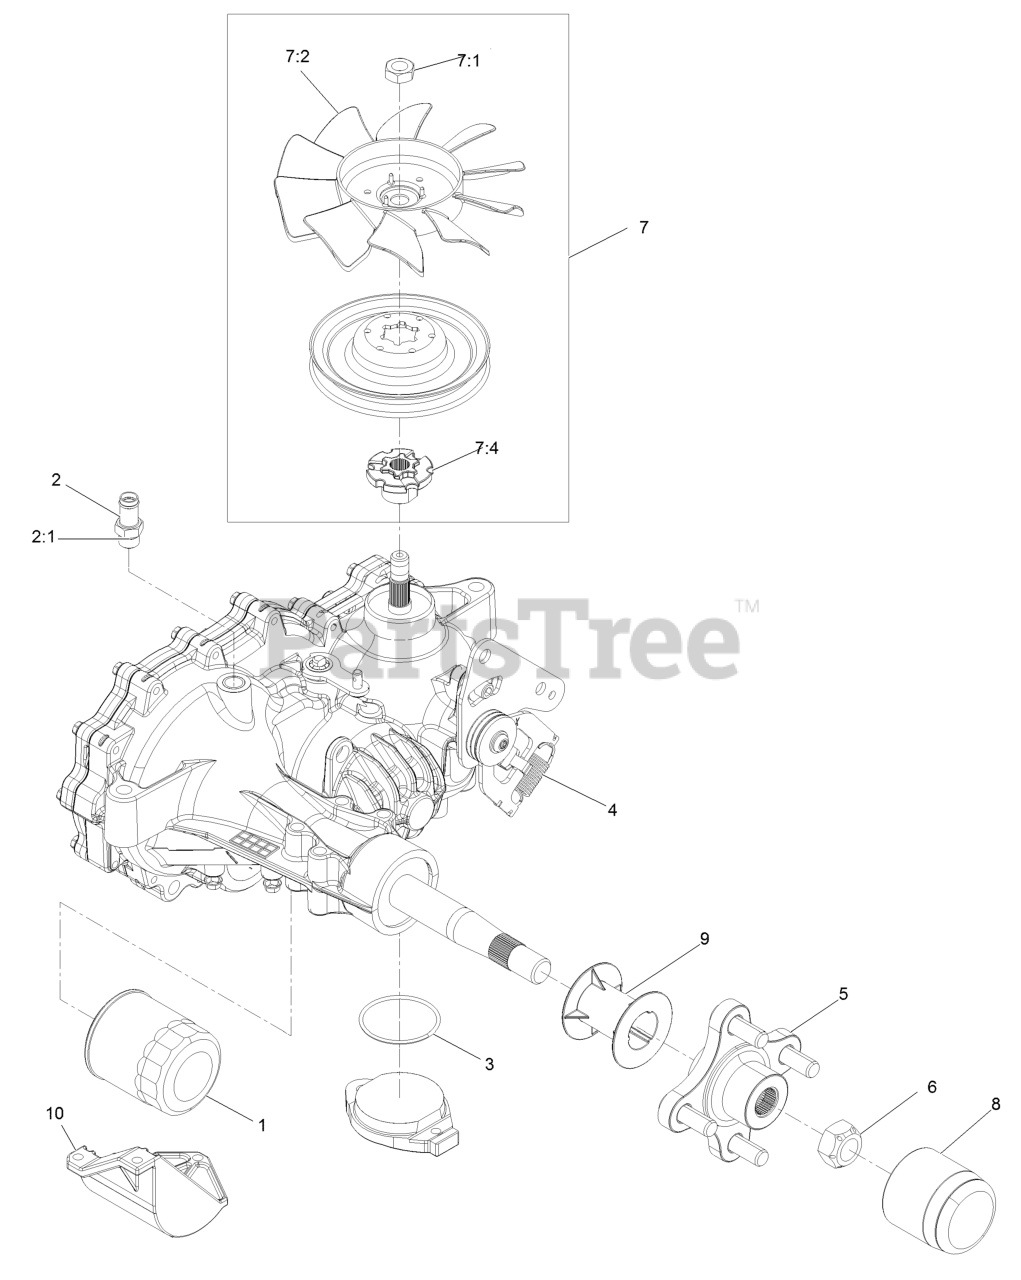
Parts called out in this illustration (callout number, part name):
1	Element-Oil Filter, HYD
2	Adapter-Straight
2:1	O-Ring
3	O Ring-Seal
4	Spring-Extension
5	Hub-Offset
6	Nut-Hub
7	Fan And Pulley Kit
7:4	Hub-Pulley
8	Cap-Long Axle
9	Tube-Axle
10	Guard-Filter, RH
99	Seal Kit
